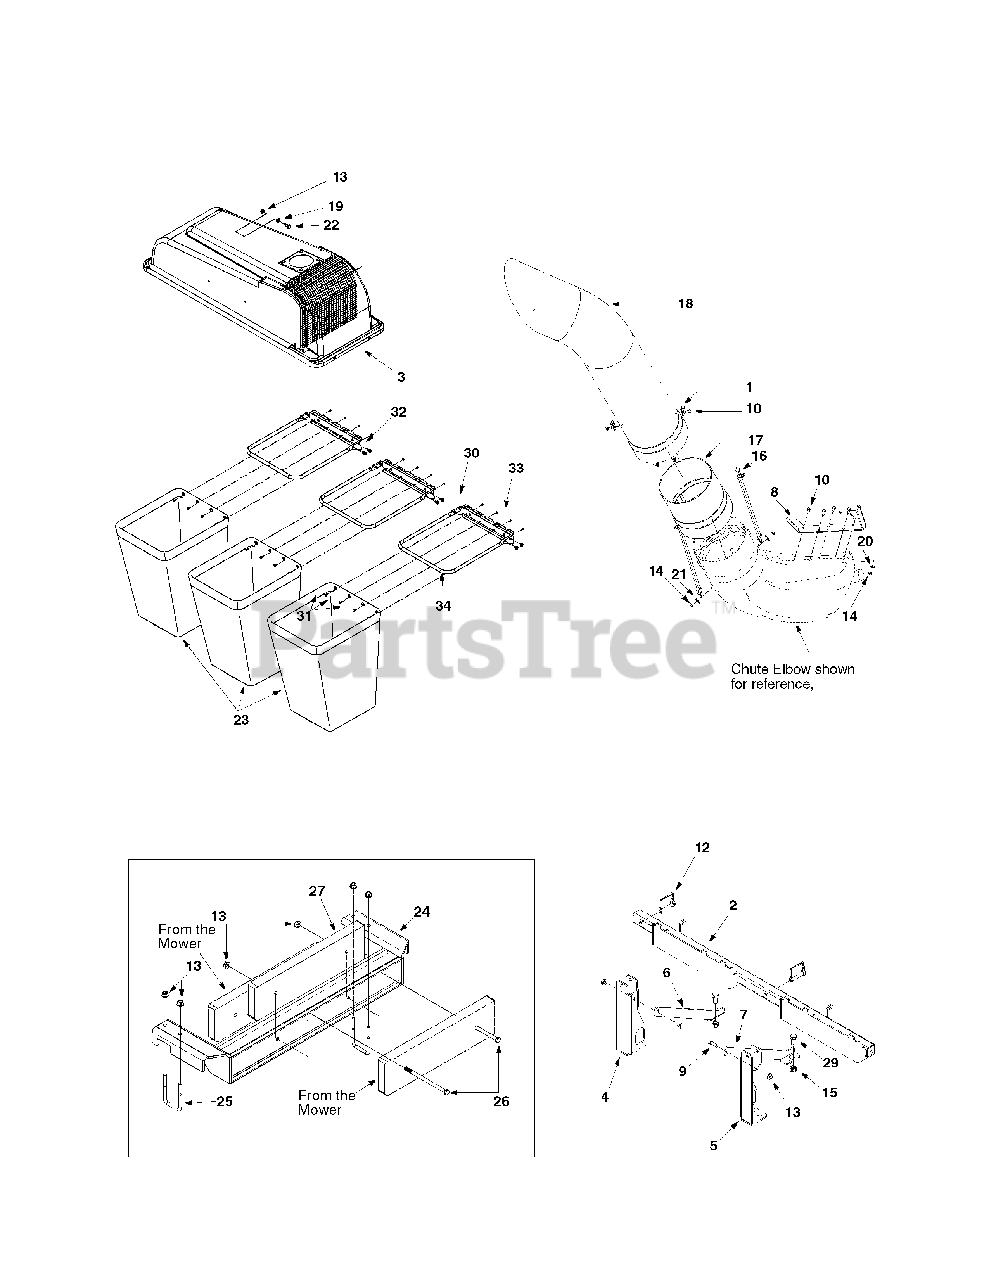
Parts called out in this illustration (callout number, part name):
1	Retainer Hook
9	Hex Bolt 3/8-16 x 1.0"
10	Hex Bolt 1/4-20 x 0.620"
11	Carriage Bolt 3/8-16 x 1.25"
12	Lock Pin
13	Top Lock Flange Nut 3/8-16
14	Flange Lock Nut 1/4-20
15	Lock Nut 1/2-13
16	Chute Strap
17	Extension Tube
18	Chute Tube
19	Belleville Washer
20	Bell Washer
21	Flat Washer
22	Shoulder Screw 3/8-16
23	Triple Grasscatcher bag
26	Hex Bolt 3/8-16 x 6.25"
27	Weight Bar
28	Carriage Bolt 3/8-16
29	Hex Screw 1/2-13
31	Machine Screw #10-24 x .50
32	Screw 5/16-18 x .625
33	Hex Nut 10-24
